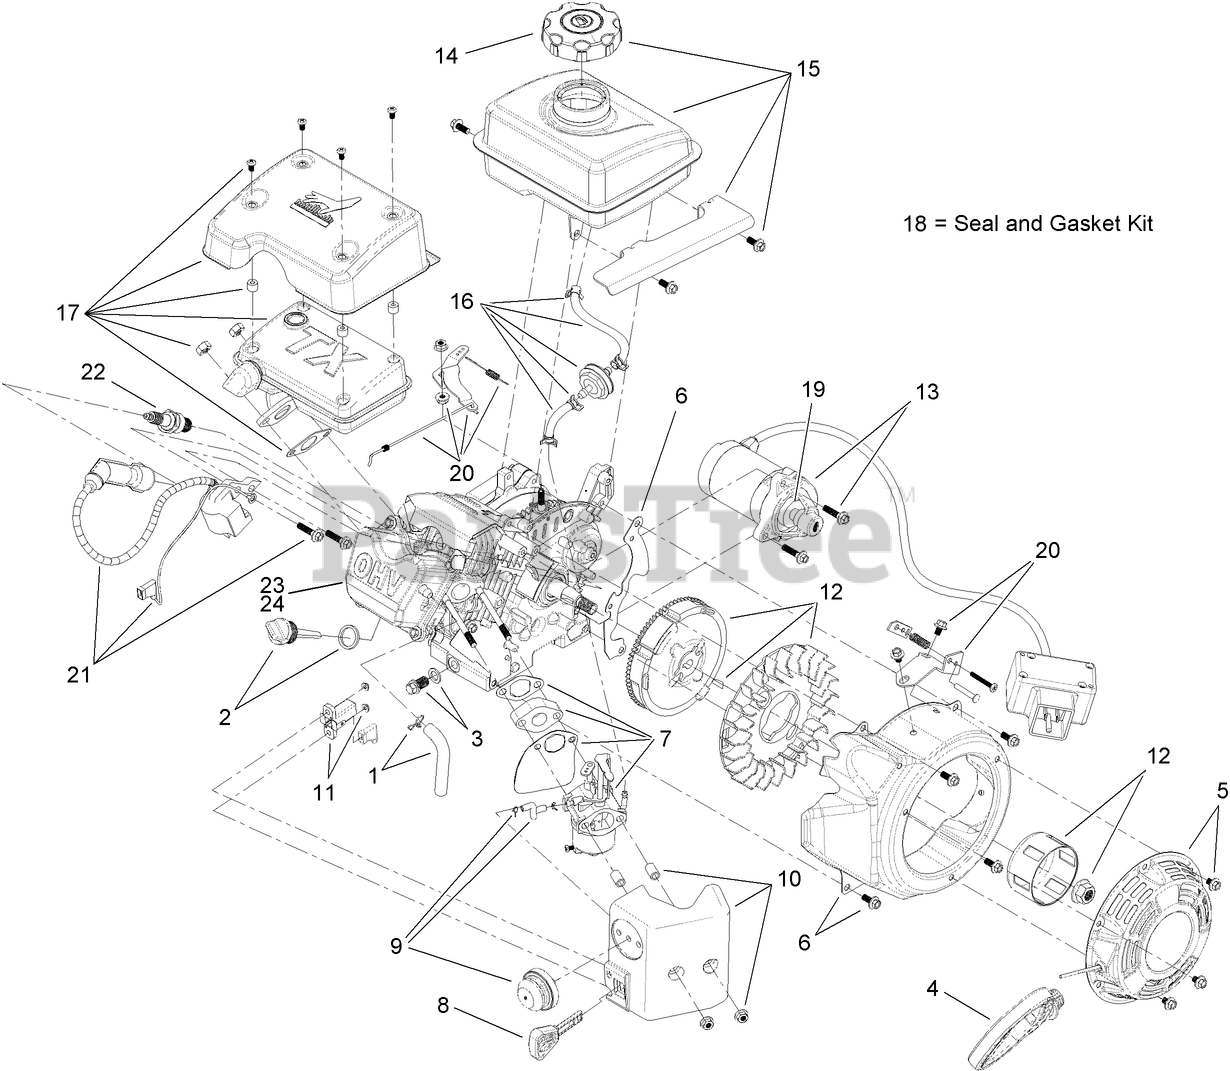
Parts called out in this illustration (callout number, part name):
1	BREATHER TUBE KIT
2	DIPSTICK AND O-RING KIT
3	DRAIN PLUG KIT
4	MITTEN GRIP KIT
5	RECOIL ASM KIT
6	BLOWER SHROUD KIT
7	COMPLETE CARB SERVICE KIT
7	CARB FLOAT AND NEEDLE KIT
7	NEEDLE REWORK KIT
8	KEY AND LANYARD KIT
9	PRIMER BULB KIT
10	HEATER BOX KIT
11	SWITCH KIT
12	FLYWHEEL KIT
19	PINION KIT
20	GOVERNOR KIT
22	SPARK PLUG
23	VALVE COVER ASM
24	GASKET-COVER, VALVE
